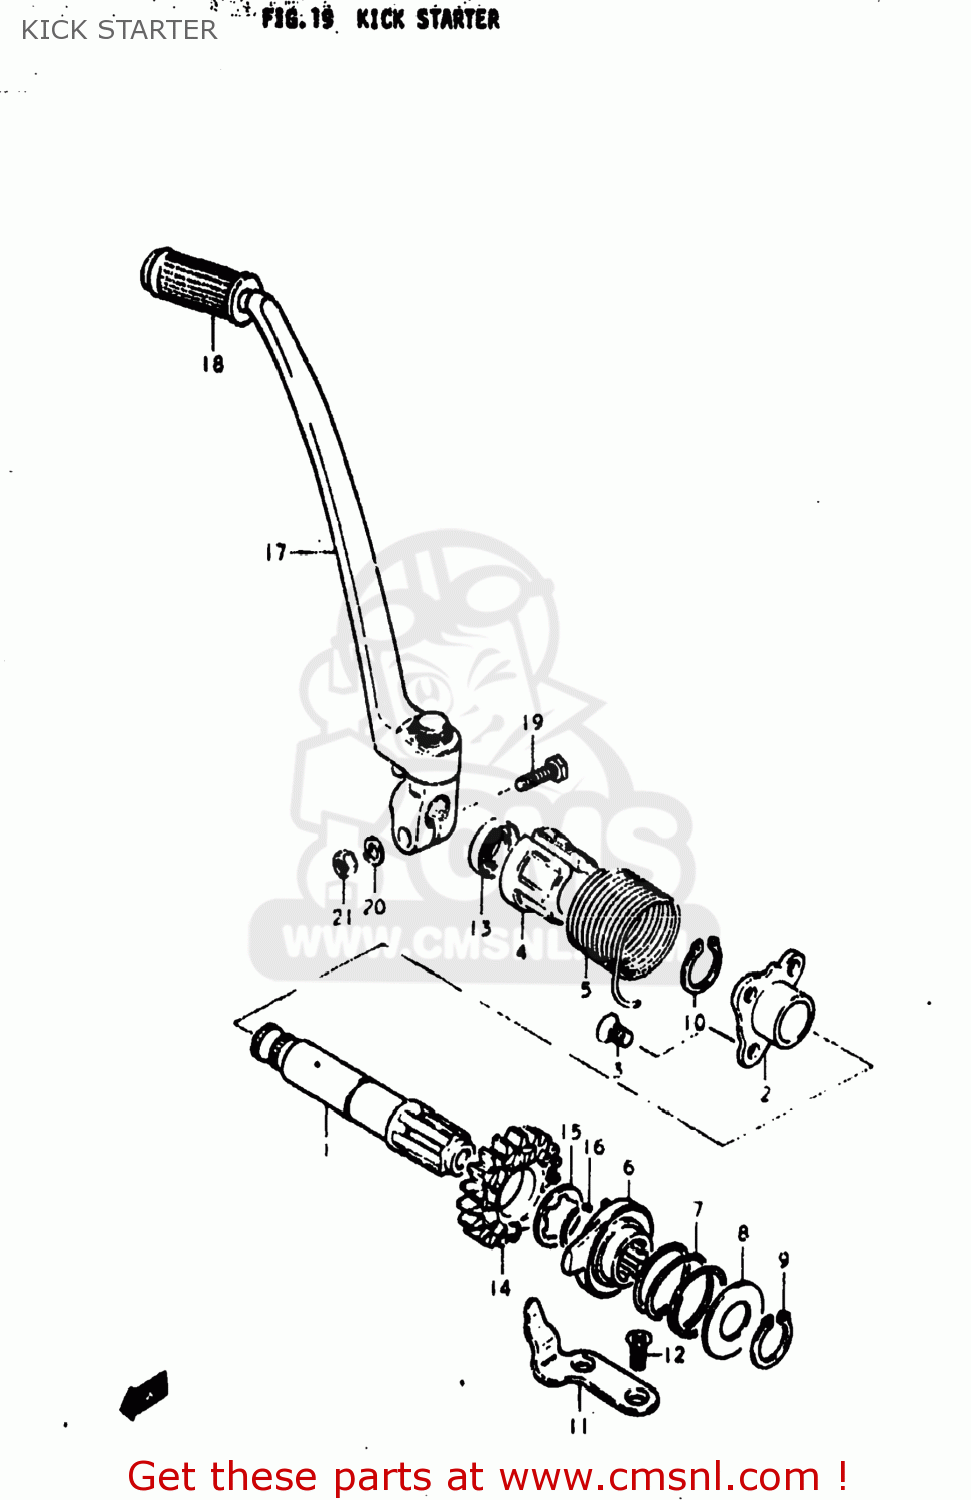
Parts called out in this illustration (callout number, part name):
1	SHAFT,KICK STARTER
2	HOLDER,KICK STARTER SHAFT
3	SCREW
4	GUIDE,STARTER SHAFT SPRING
5	SPRING
6	STARTER,KICK
7	SPRING
8	WASHER
9	CIRCLIP
10	CIRCLIP
11	GUIDE,STARTING SPRING
12	SCREW
13	SEAL,OIL(20X27X5)
14	GEAR,KICK STARTER DRIVE
15	WASHER,LOCK
16	CIRCLIP
17	LEVER ASSY,KICK STARTER
18	RUBBER,KICK STARTER PEDAL
19	BOLT,M10X1.25X
20	LOCK WASHER
21	NUT
